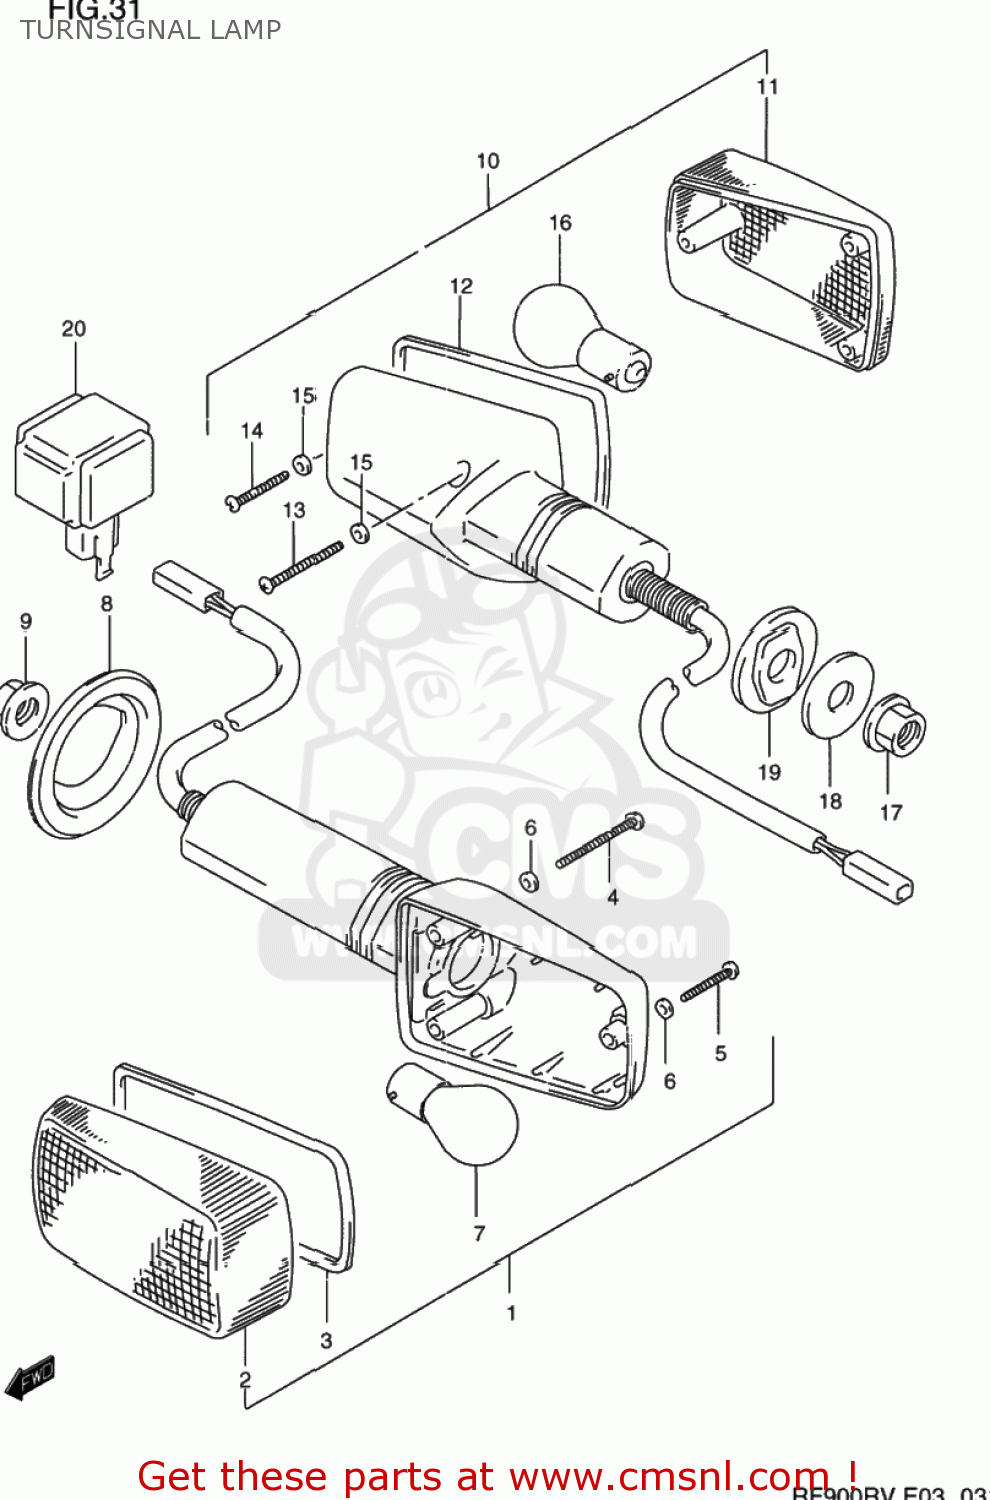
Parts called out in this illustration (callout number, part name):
1	LAMP ASSY,FR TURN SIGNAL
2	LENS
3	GASKET (NAS)
4	SCREW(3X30)
5	SCREW
6	GASKET (NAS)
7	BULB(12V21W)
8	GROMMET
9	NUT
10	LAMP ASSY,RR TURNSIGNAL
11	LENS
12	GASKET (NAS)
13	SCREW(3X30)
14	SCREW
15	GASKET (NAS)
16	BULB(12V21W)
17	NUT
18	WASHER(10.5X30X2.3)
19	SPACER,RR TURNSIGNAL
20	RELAY ASSY,TURNSIGNAL LAMP
